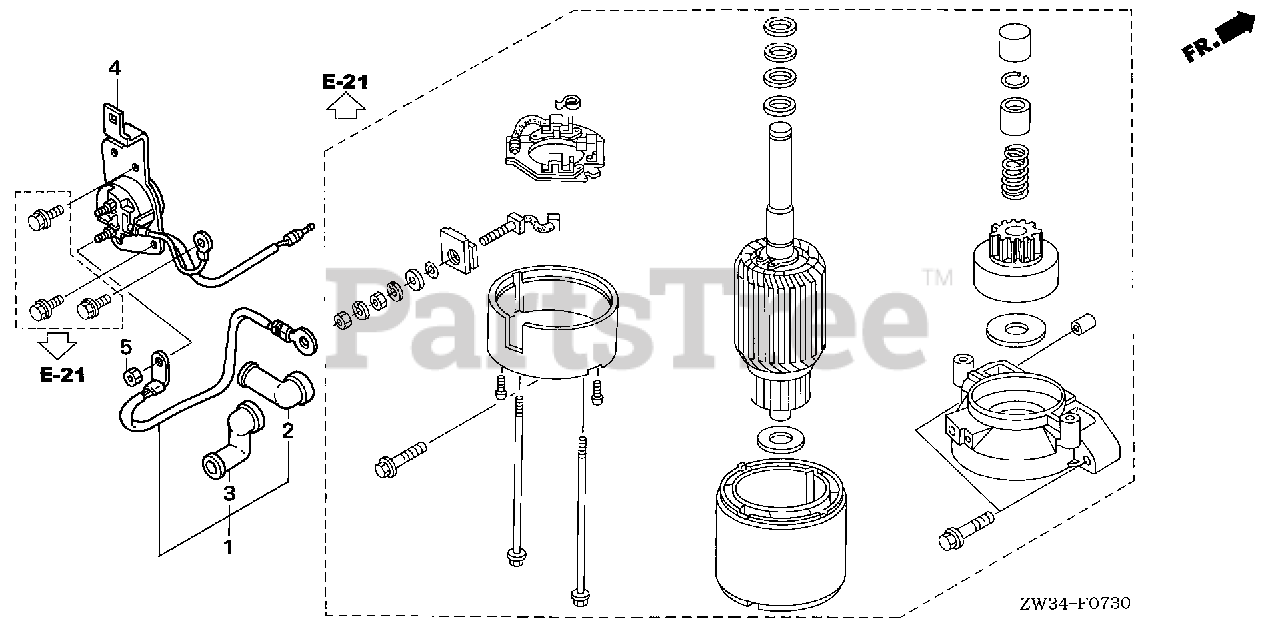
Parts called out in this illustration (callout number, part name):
1	WIRE, MAGNETIC SWITCH (120MM)
2	COVER, STARTER MOTOR TERMINAL
3	COVER, MAGNETIC SWITCH TERMINAL
4	SWITCH ASSY., STARTER MAGNETIC
5	NUT, HEX. (6MM)
